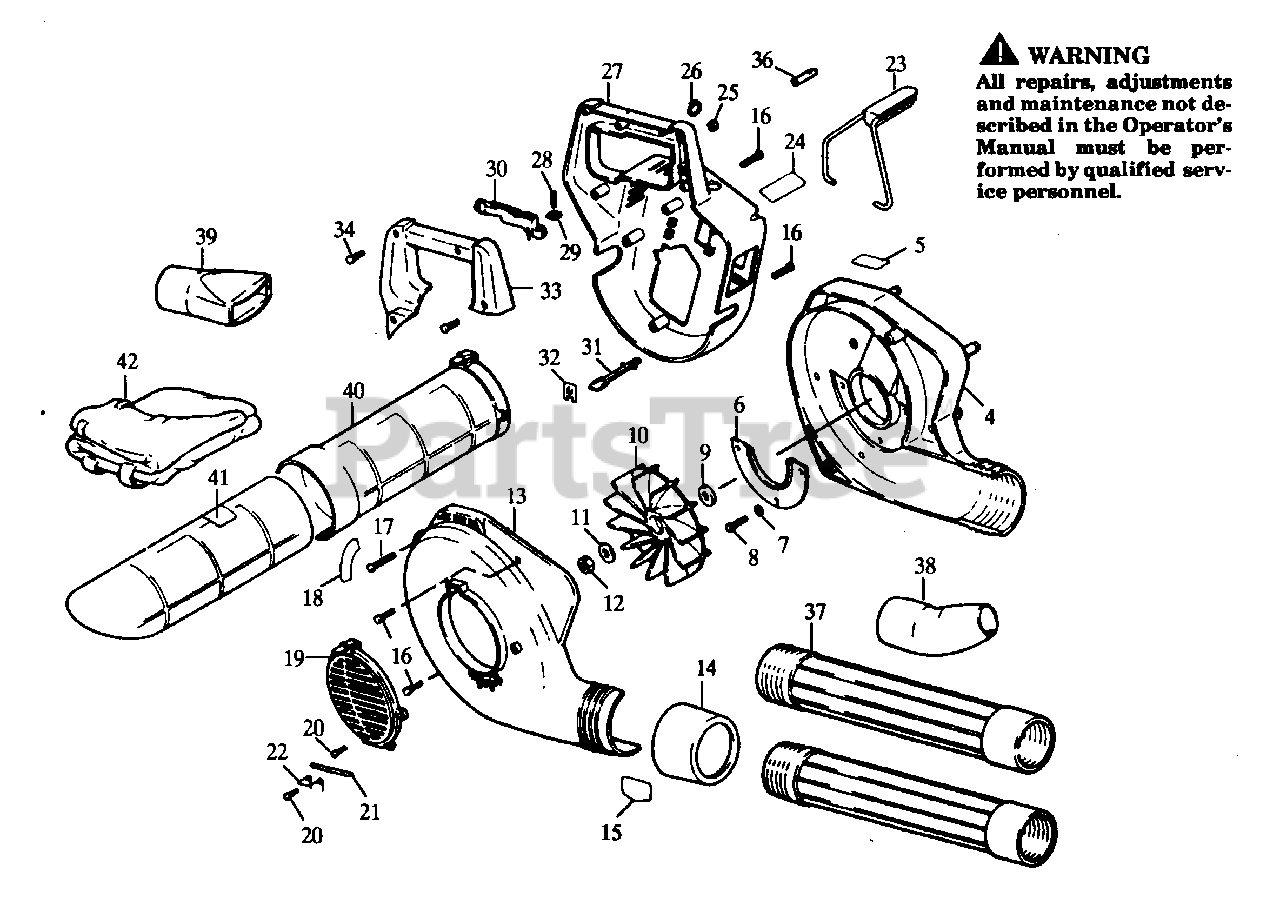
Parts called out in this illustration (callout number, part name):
4	Main Support Housing
5	Starting Instructions Decal
6	Engine Mount Plate
7	Lockwasher
10	Impeller Ass'y.
13	Inlet Cover Housing
15	Exhaust Label (Model GB150)
15	Exhaust Label (Model GB350)
18	Caution Label (Not a serviceable part)
19	Inlet Cover
21	Hinge Pin
22	Spring Return
23	Assist Handle Ass'y.
24	Nameplate Label
26	Split Ring
27	Engine Cover Housing
30	Throttle Trigger Ass'y.
31	Tickler Lever
33	Handle Cover Housing
37	Outlet Tube
38	Concentrator Nozzle
39	Nozzle Diffuser (Model GB350)
40	Vacuum Tube (Model GB350)
41	Nameplate Label (Model GB350) (Not a serviceable part)
42	Vacuum Bag (Model GB350)
